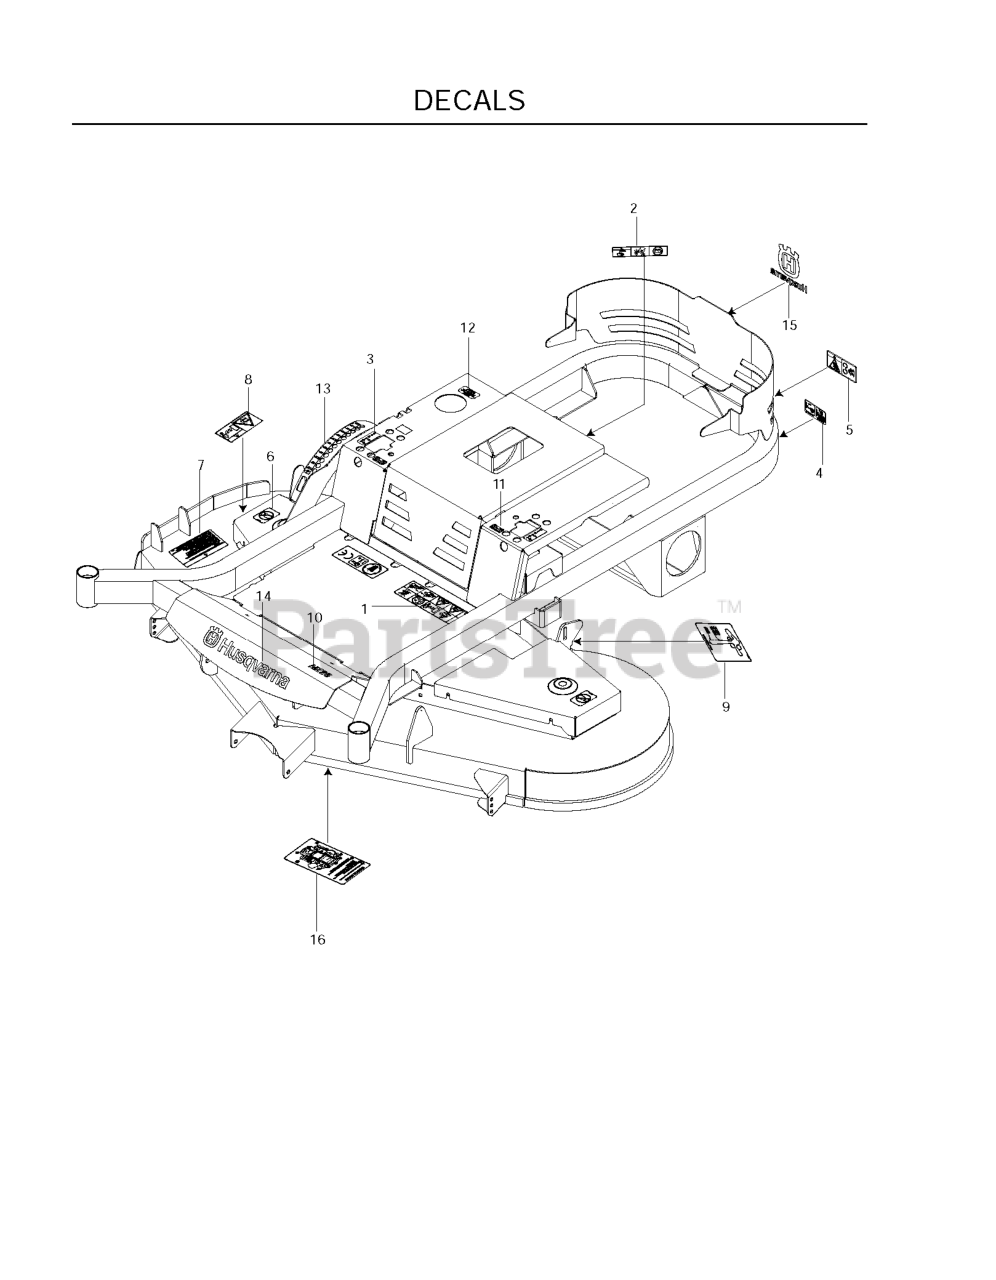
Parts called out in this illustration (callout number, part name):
1	DECAL, WARNING
2	EURO DECAL-BATTERY WARNIN6
3	DECAL, MOTION CONTROL
4	DECAL
5	DECAL, BELT DRIVE
6	DECAL, NO STEP
7	DECAL, DISCHARGE, MULTILINGUAL
8	DECAL, EURO SEVERING
9	DECAL, BELT ROUTING
10	DECAL, MZ25
11	DECAL, F.S.T.
12	DECAL, OIL TANK
13	DECAL, HEIGHT MZ, CE
14	DECAL.HOOD.LOGO.ORANGE.HUSQVAR
15	DECAL, CROWN H 70MM
16	DECAL, SERVICE
